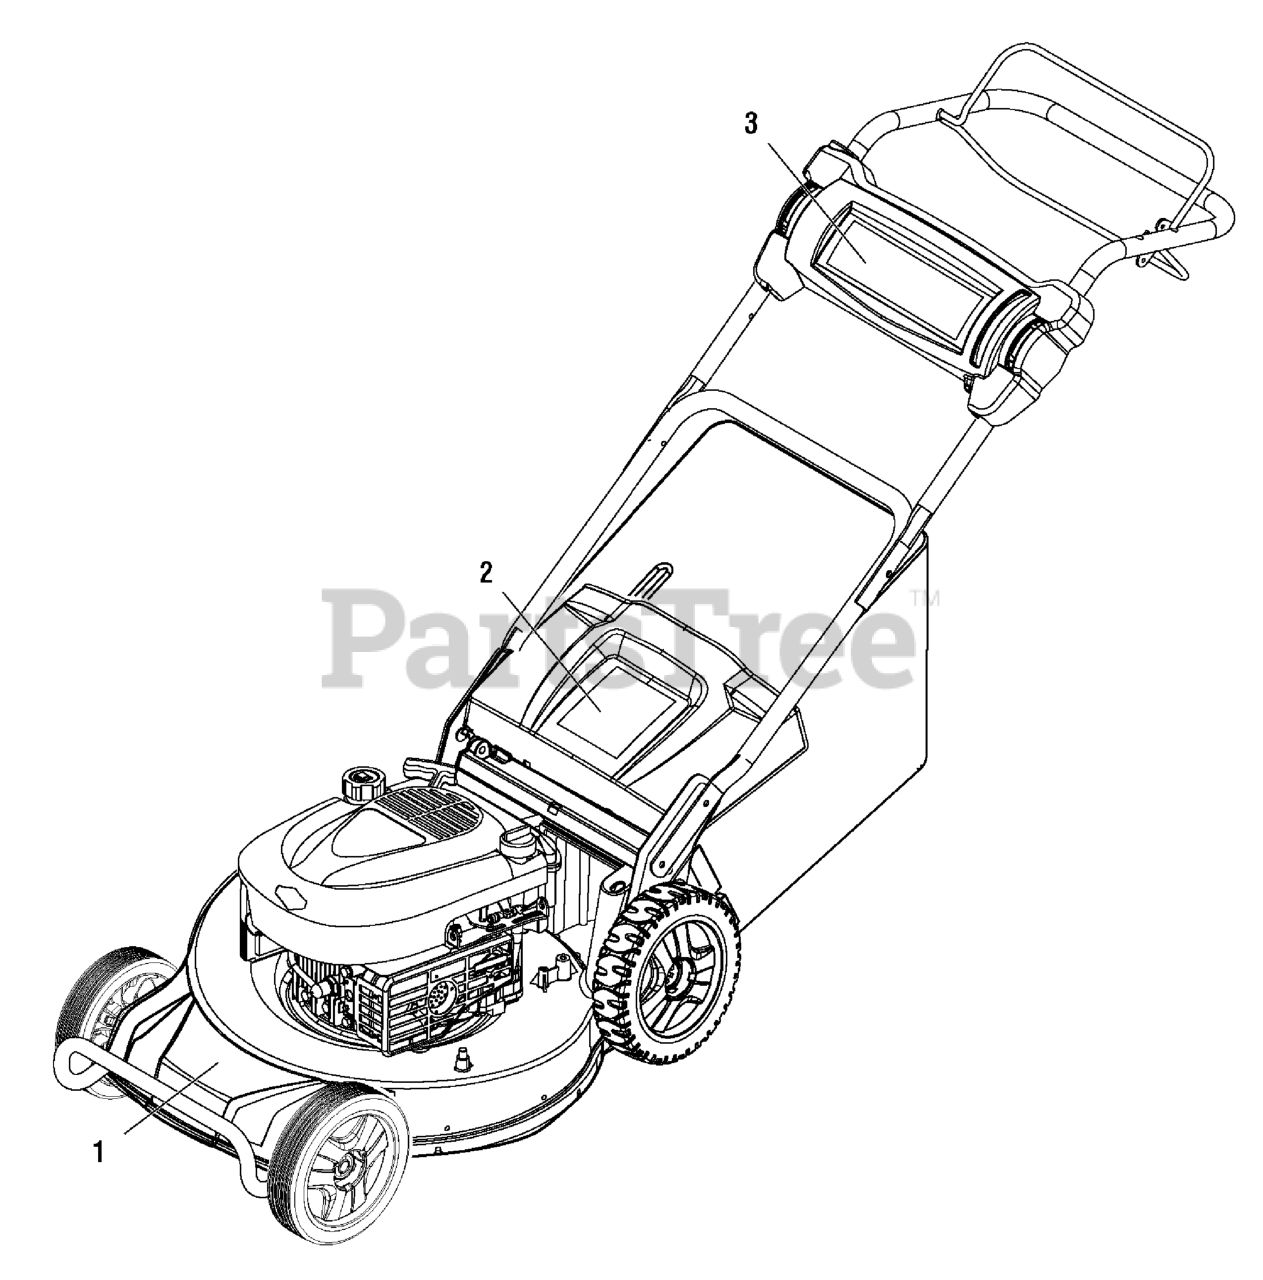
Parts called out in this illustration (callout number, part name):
1	DECAL, Logo, Deck
2	DECAL, Safety
3	DECAL, Console
